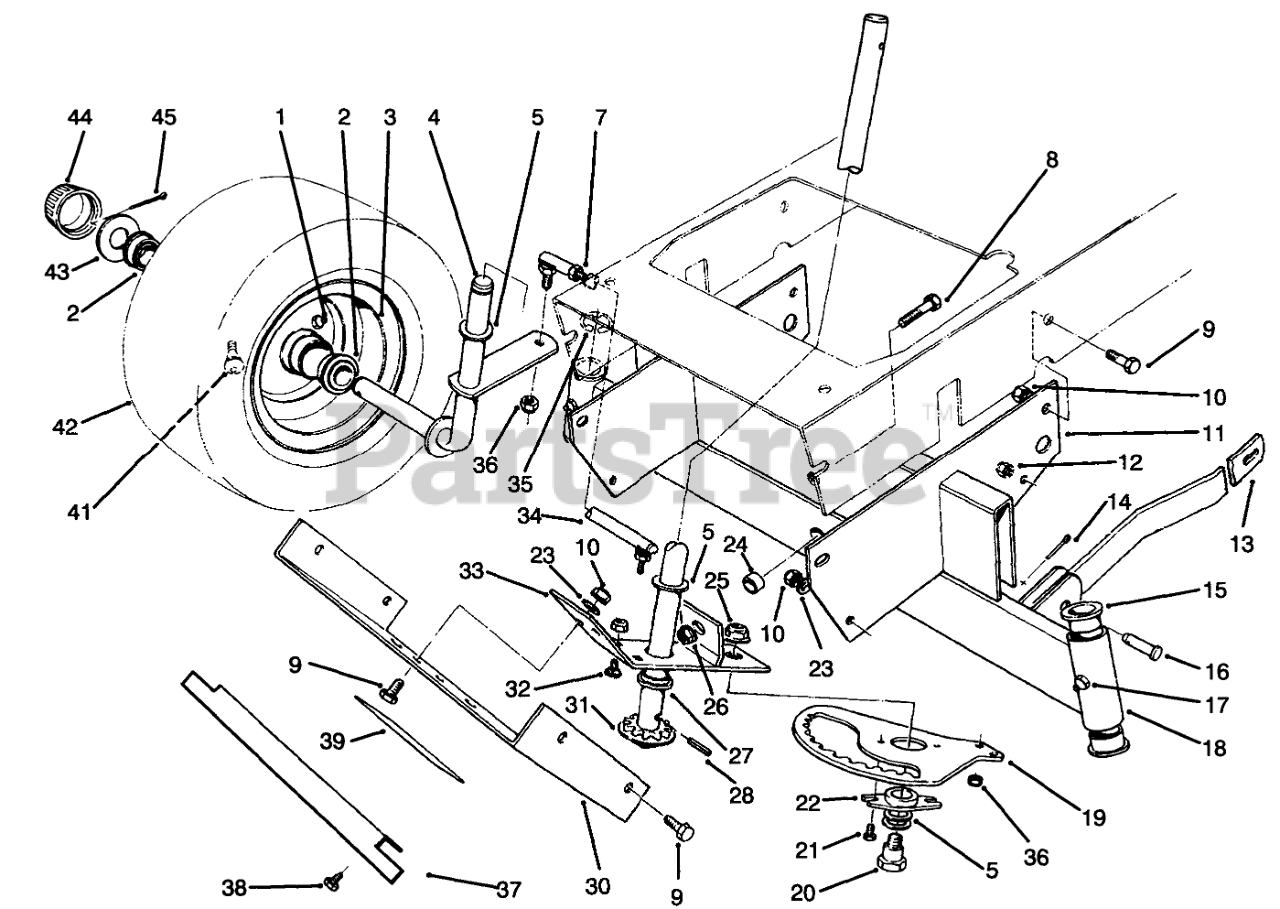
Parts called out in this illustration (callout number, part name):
1	FITTING-GREASE
2	Bearing
4	Spindle RH
5	WASHER-THRUST
7	NUT-JAM
8	SCREW-HH
9	SCREW-HH
10	NUT-LOCK, NI
11	Support
12	NUT-HEX
13	Arm-Suspension, Front
14	PIN-COTTER
15	BEARING-FLANGE
16	PIN-CLEVIS
17	GREASE FITTING
18	Axle-Front (Incl. Ref. #15 & 17)
19	Rack-Steering
21	SCREW-HWH
22	BUSHING-SECTOR
23	WASHER-PLAIN
24	SPACER-AXLE, FRONT
25	NUT-HF
26	NUT-HF
27	BEARING-FLANGE
28	PIN-ROLL, SLOTTED
30	Cover-Front
31	STRG SHAFT WA
32	SCREW-CARR
33	Bracket-Rack, Steering (Incl. Ref. #27)
34	Tie Rod-Adjustable (Incl. Ref. #7)
35	E-RING
36	NUT-LOCK
37	Guard-Front
38	SCREW-HWHTF
39	DECAL - IMPORTANT
41	STEM-VALVE
42	TIRE,PNEU.11X4.00X5
43	WASHER-PLAIN
44	CAP-HUB
45	PIN-COTTER
